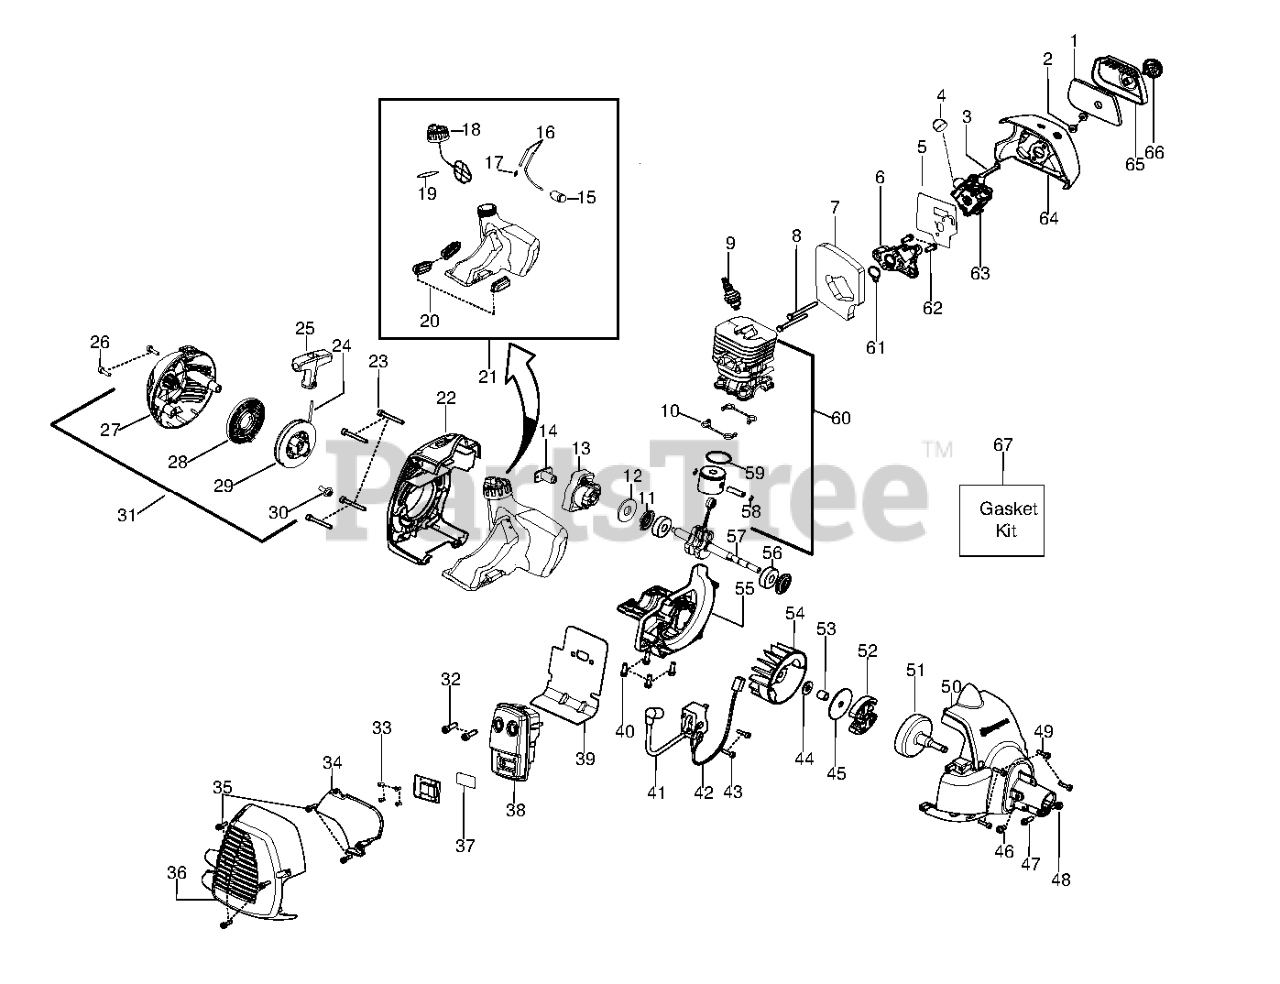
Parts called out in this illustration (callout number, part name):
1	FILTER AIRBOX
3	CHOKE LEVER
4	PURGE BULB ZAMA
5	KIT GASKET 28CC
6	CARB ADAPTOR
7	KIT GASKET 28CC
8	BOLT CARB ADAPTOR
9	Accy - Spark Plug (RCJ6-Y)
10	KIT GASKET 28CC
11	KIT GASKET 28CC
12	WASHER FLAT
13	ASSY STARTER CUP
14	COUPLING-STARTER
15	FUEL PICK-UP ASSY
16	KIT-LINE(FUEL)
17	FUEL LINE FITTING
18	ASSY-CAP W/RETAINER
19	KIT GASKET 28CC
20	ISOLATOR FUEL TANK
21	KIT FUEL TANK HVA
22	REAR SHROUD ORANGE
25	STARTER HANDLE GRAY
26	SCREW M5-0.8X30MM
27	STARTER HOUSING
28	%KIT STARTER SPRING
29	KIT STARTER PULLEY
31	ASSY-STARTER HSG.
32	BOLT MUFFLER
33	SCREW-6-19X5/16PLAST PA
34	SHIELD HEAT
35	SCREW M4 X 1.75 PT 16MM
36	GUARD-MUFFLER
37	KIT SPARK ARRESTOR SCREEN
38	KIT MUFFLER W/CATALYST
39	KIT GASKET 28CC
40	SCREW-M5-0.8 X 25MM(TAP)
41	IGNITION MODULE MB45
42	ASSY MODULE LEAD WIRE
43	SCREW M4 X .70 TT 16MM
44	WASHER CLUTCH
45	WASHER-CLUTCH
48	LOCKNUT-HEX 10-24
49	SCREW M4 X .70 TT 16MM
50	FAN HSG ASSY
51	ASSY-CLUTCH DRUM
52	%KIT CLUTCH ASSY
53	SPACER FLYWHEEL
55	CRANKCASE CAST LE28
56	BEARING RADIAL BALL (6201)
57	ASSY CRANKSHAFT FORGED ROD
58	WRIST PIN RET.
59	RING PISTON
60	KIT PISTON & CYLINDER
61	KIT GASKET 28CC
62	SCREW-M5-0.8 X 25MM(TAP)
63	CARBURETOR KIT W38
64	AIRBOX HVA 128 HUSKY GRAY
65	COVER-AIR BOX
66	KNOB ASSY AIRBOX COVER
67	KIT GASKET 28CC
